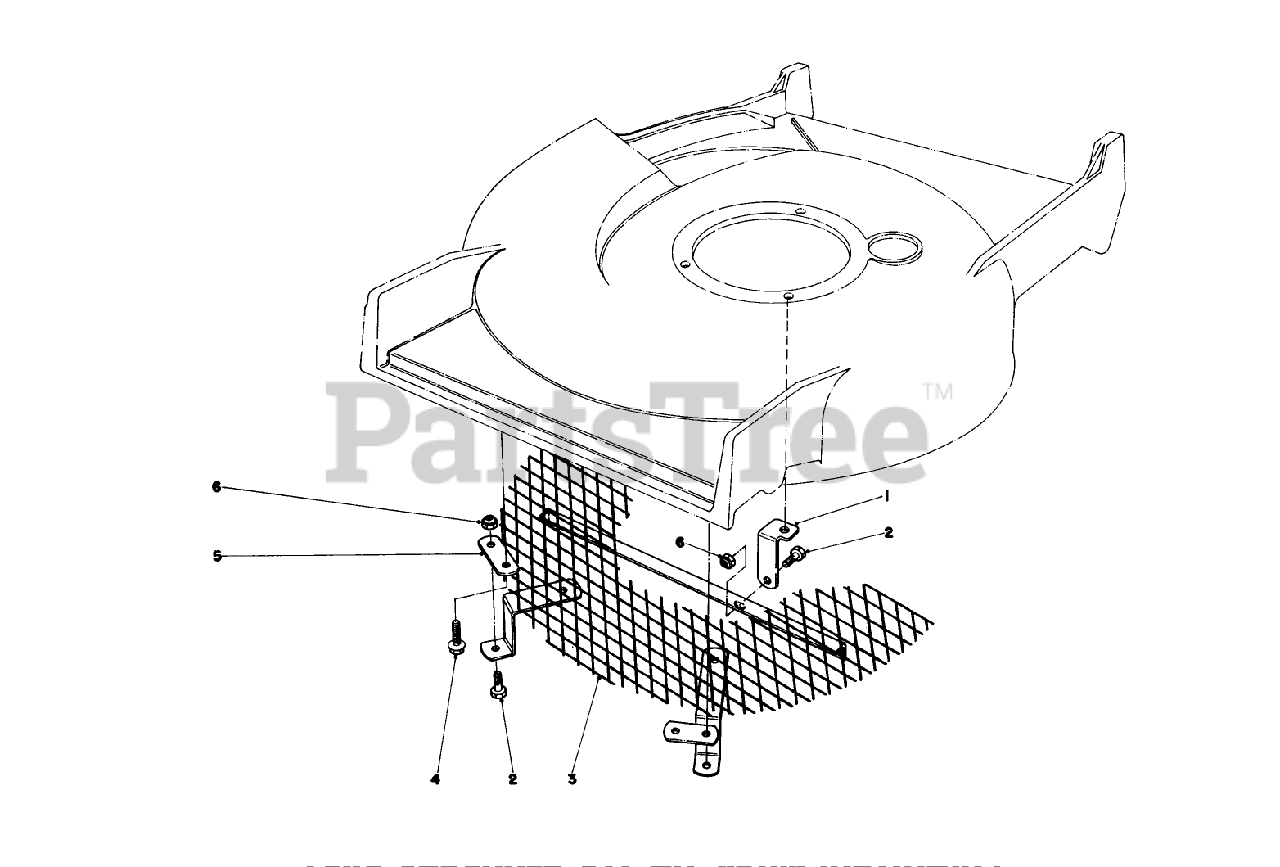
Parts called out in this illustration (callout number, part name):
2	SCREW-HH
4	SCREW-THD ROLL, HWH
6	NUT-LOCK, NI
